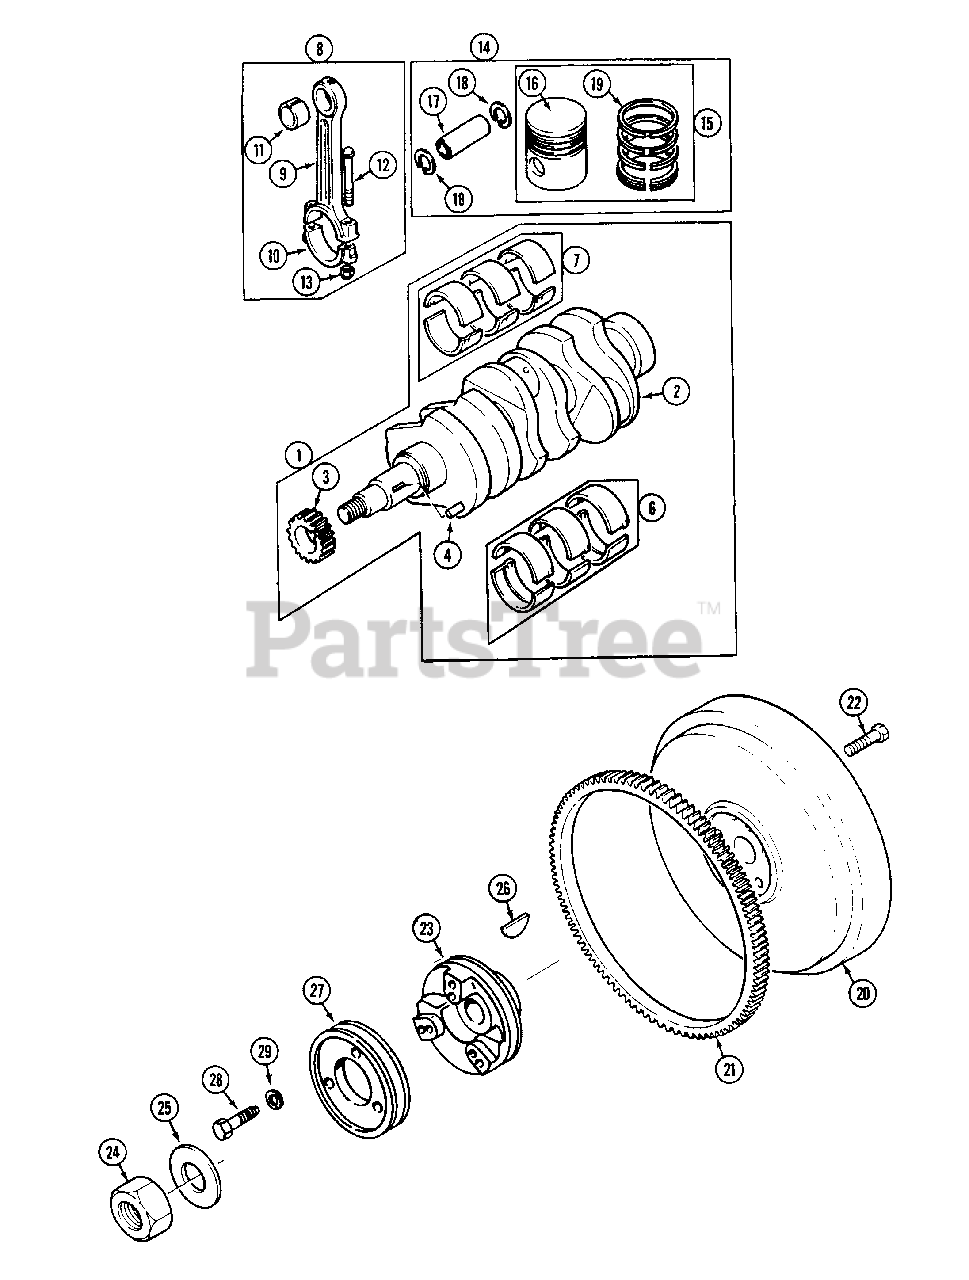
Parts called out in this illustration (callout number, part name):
1	KIT - crankshaft
2	CRANKSHAFT
3	GEAR
4	KEY
6	KIT - bearing (standard)
7	KIT - bearing (standard)
8	ROD - connecting
9	ROD
10	CAP
11	BUSHING
12	SCREW
13	NUT
14	KIT - piston (standard)
15	PISTON ASSEMBLY
16	PISTON
17	PIN
18	CIRCLIP
19	KIT - rings (standard)
20	FLYWHEEL
21	RING
22	SCREW
23	PULLEY
24	NUT
25	WASHER
26	KEY
27	PULLEY - engine
28	BOLT - 5/16" - 18 x 1-1/4
29	LOCKWASHER - 5/16"
